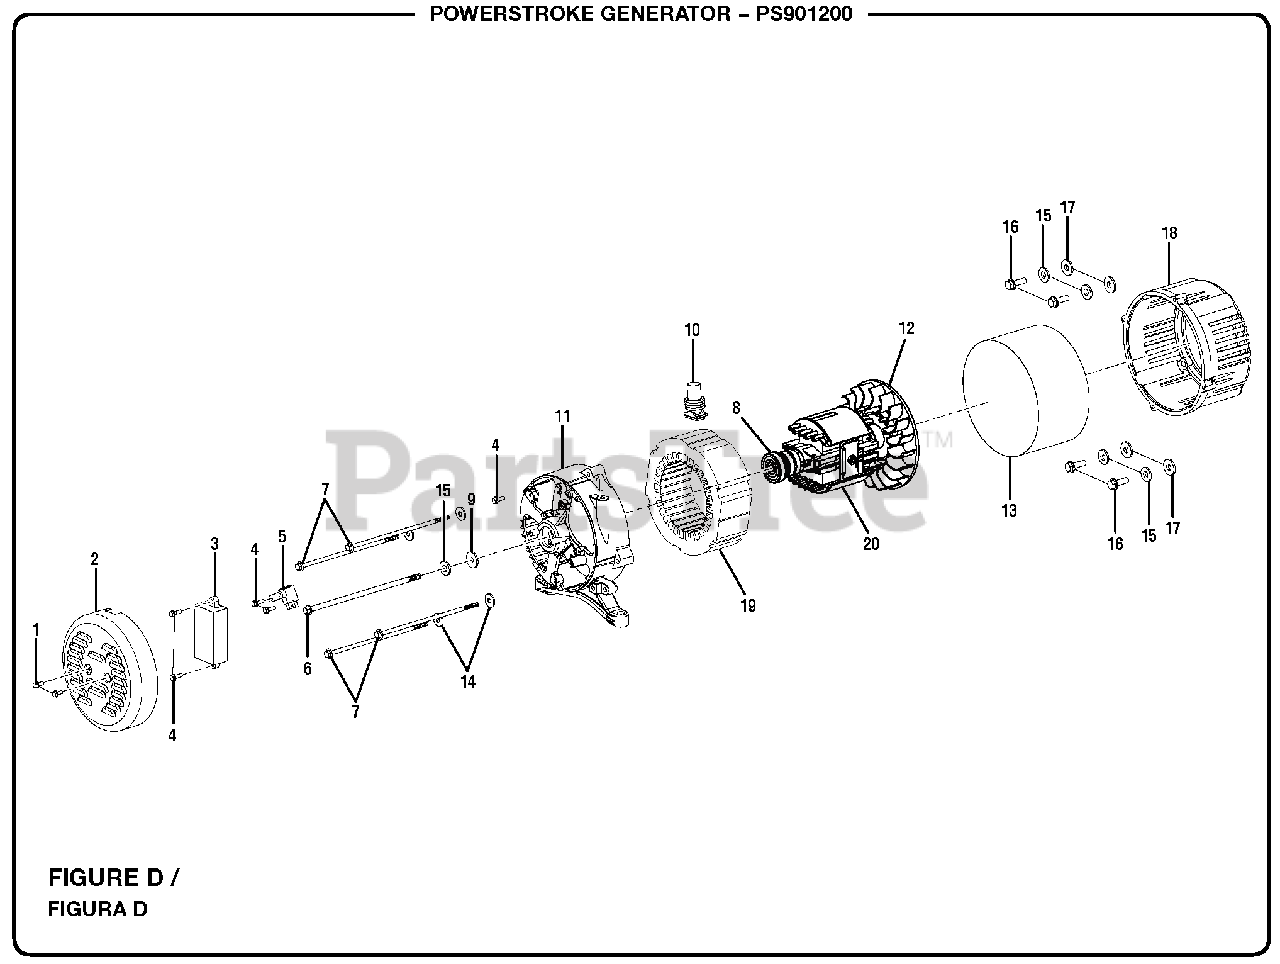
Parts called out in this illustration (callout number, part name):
1	Bolt (M5 x 12 mm, Flange Hd.)
2	Brush Cover
3	Automatic Voltage Regulator
4	Bolt (M5 x 16 mm, Flange Hd.)
5	Brush Assembly
6	Rotor Bolt (M8 x 180 mm)
7	Stator Bolt (M6 x 105 mm)
8	Ball Bearing
9	Washer (M8)
10	Rubber Boot
11	Bearing Support
14	Spring Washer (M6)
15	Spring Washer (M8)
16	Bolt (M8 x 20 mm, Flange Hd.)
17	Washer (M8)
18	Adaptor Housing
